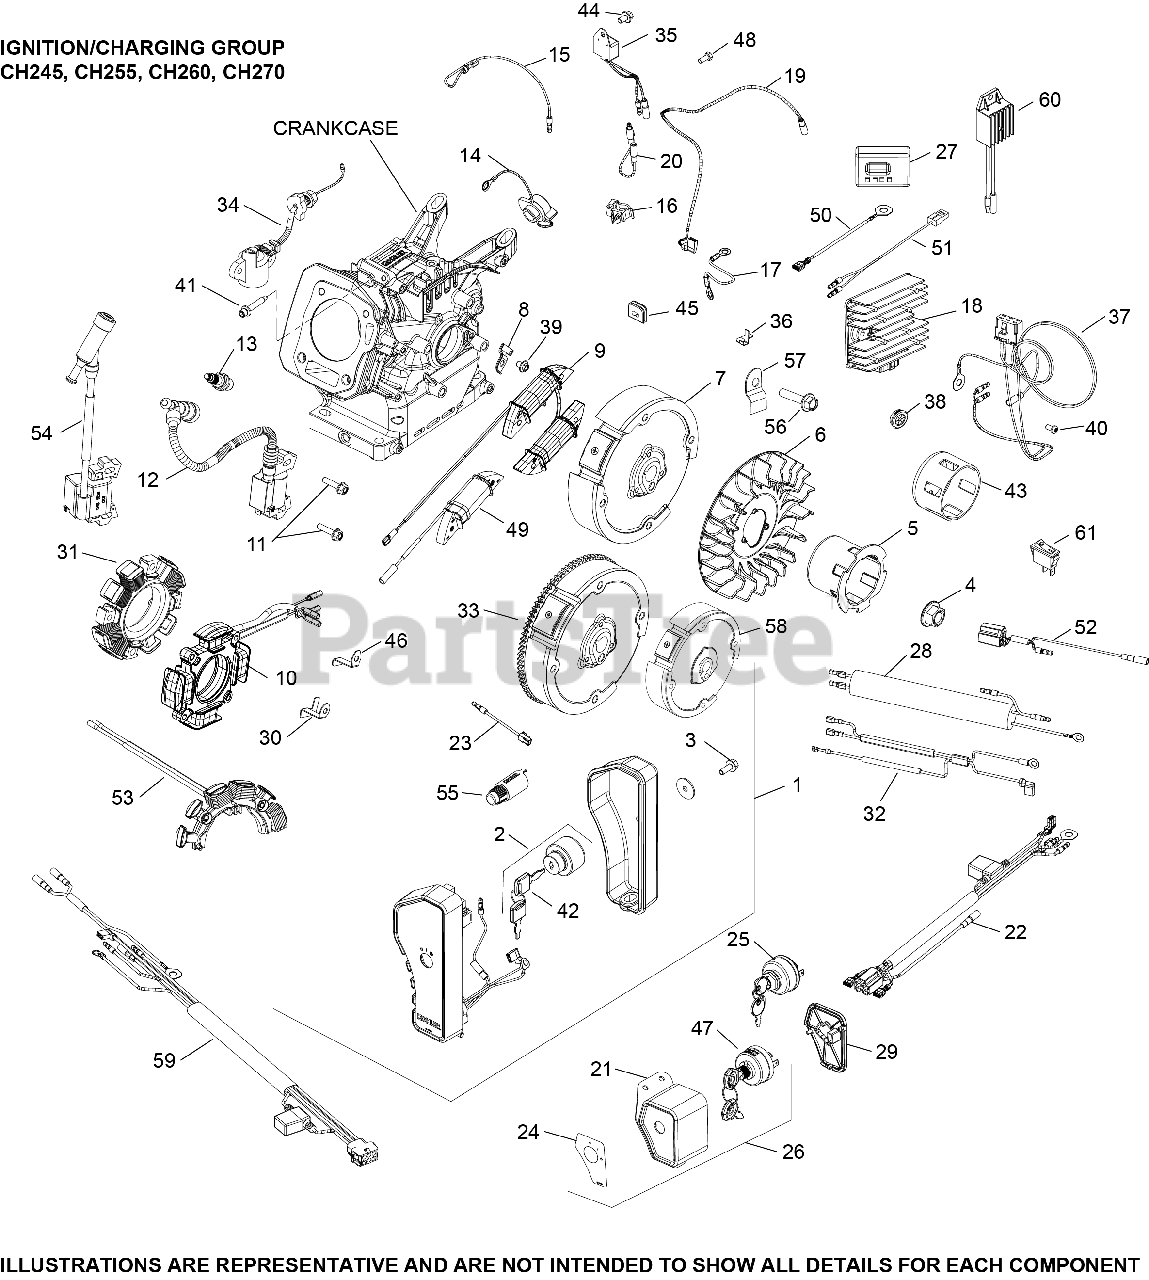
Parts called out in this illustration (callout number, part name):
4	NUT, FLYWHEEL (W/SERRATIONS)
6	FAN, FLYWHEEL
7	FLYWHEEL ASSEMBLY
11	SCREW, M6 X 25 USE 25 086 436-S
12	MODULE, IGNITION
13	PLUG, SPARK 12MM RFI
34	SWITCH, OIL SENSOR ASSEMBLY
35	CONTROL, OIL ALERT UNIT
36	CLIP, WIRE HARNESS - DISCONTINUED
37	WIRING HARNESS, MICROSWITCH
41	SCREW, HEX SOCKET HEAD CAP
43	CUP, STARTER
44	SCREW, FLG M6X1.0X10
